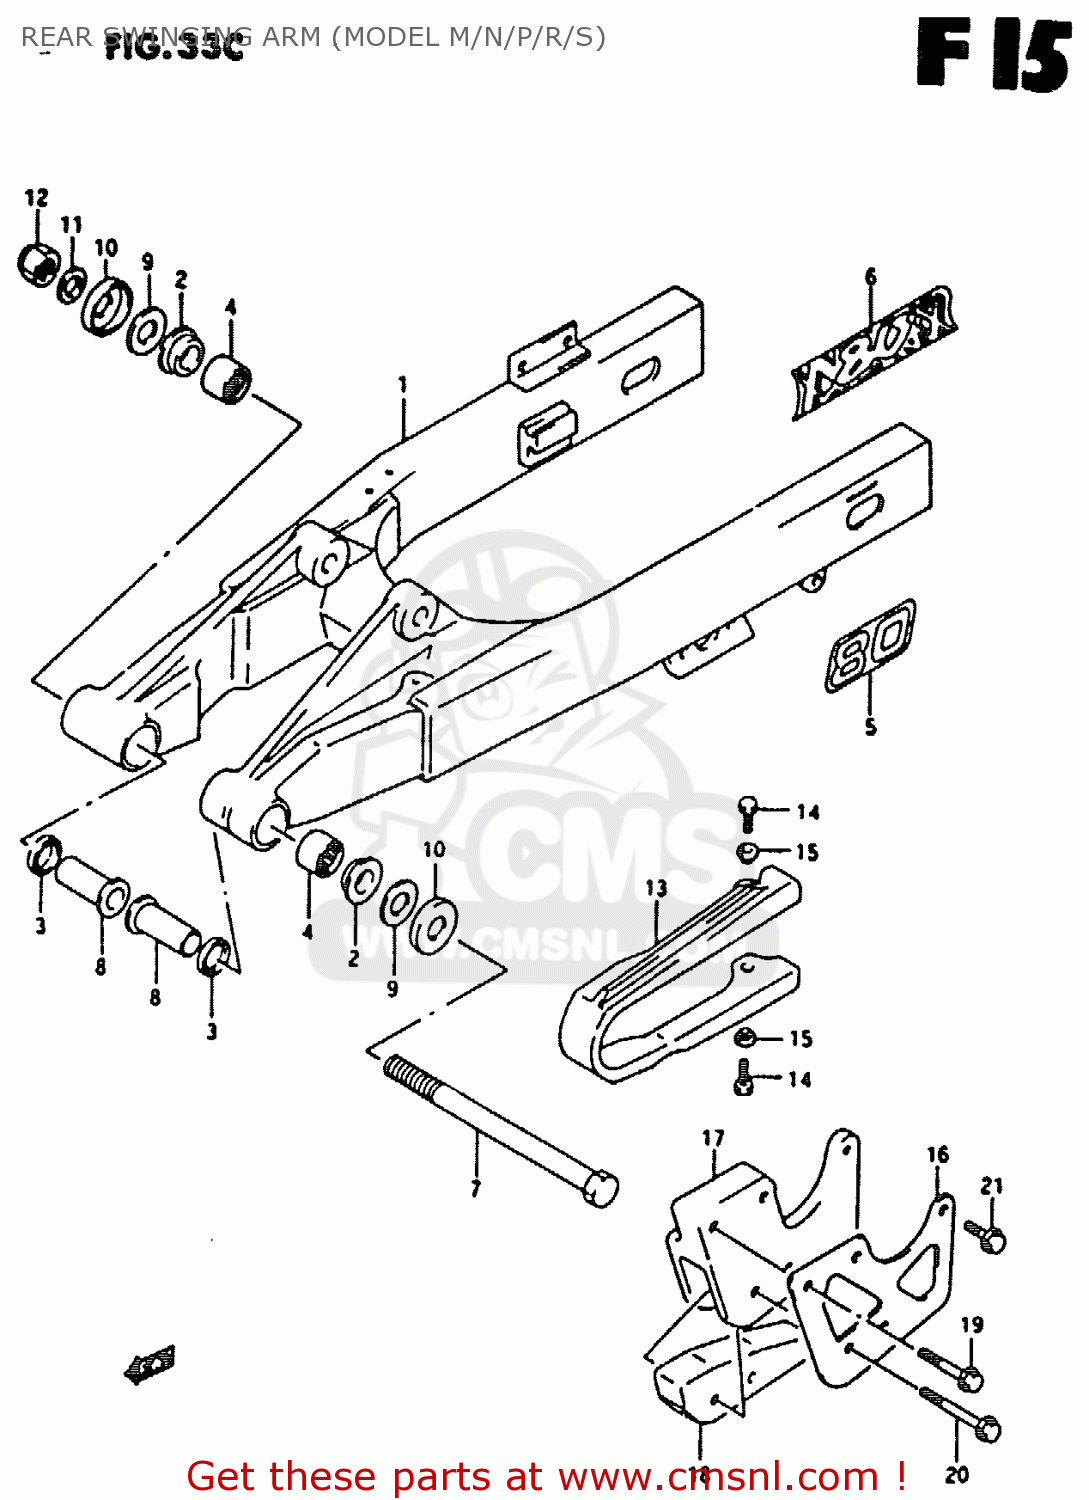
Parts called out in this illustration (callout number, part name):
1	SWINGINGARM ASSY,RR
2	BUSHING,SWGARM PIVOT
3	SEAL,OIL(17X24X3)
4	BEARING(17X24X30)
5	EMBLEM,SWING ARM
6	EMBLEM
7	SHAFT,RR SWINGINGARM PIVOT
8	SPACER,RR SWGARM PIVOT
9	WASHER
10	COVER,SWGARM PIVOT
11	WASHER
12	NUT 12MM
13	BUFFER,CHAIN TOUCH DEFENSE
14	BOLT
15	WASHER
16	PLATE,GUIDE CHAIN OUTER
17	GUIDE,CHAIN
18	DEFENSE,CHAIN GUIDE
19	BOLT
20	BOLT
21	BOLT
